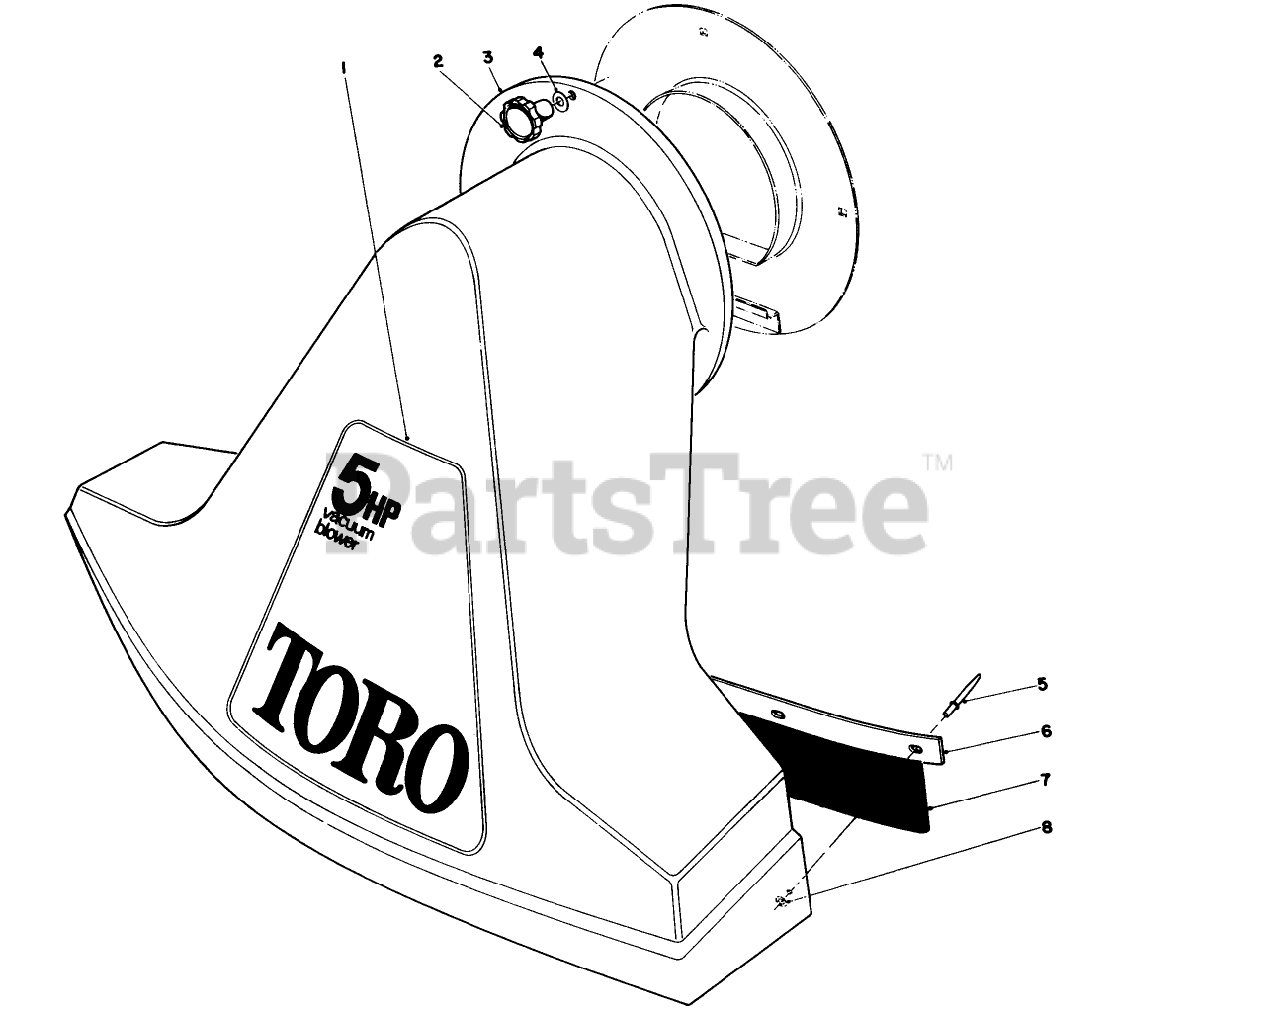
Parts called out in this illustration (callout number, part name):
3	SNOUT ASM
5	POP RIVET 3/16X.375LG
7	FLAP-RUBBER
8	WASHER-FLAT
